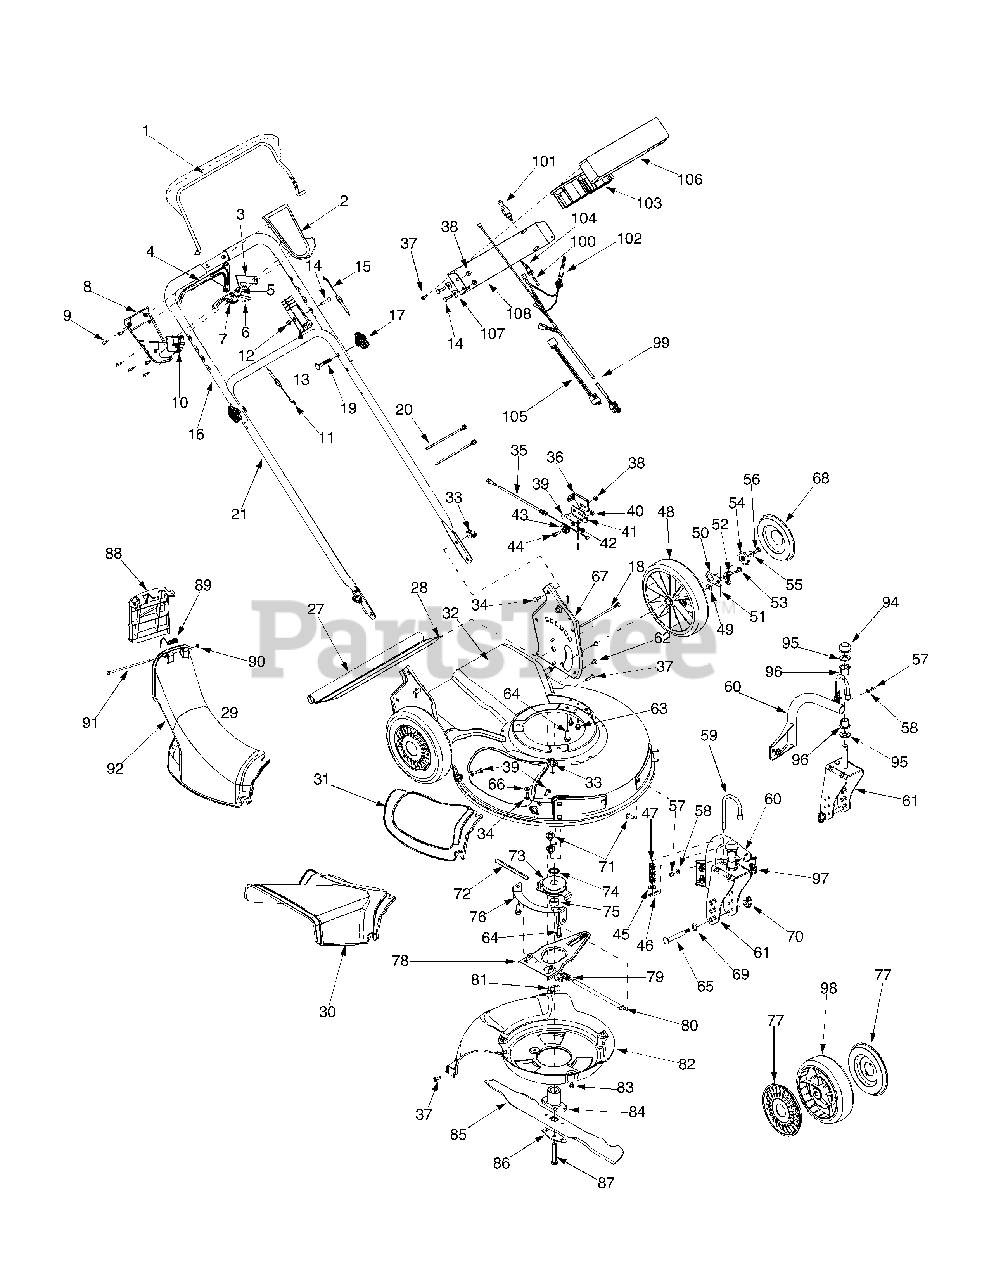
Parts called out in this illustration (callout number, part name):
1	Control Handle
2	Upper Control Handle
3	6 Spd. Rack Cable Bracket
4	Control Lever
5	Gear Insert
6	Shift Lever Spring
7	6 Speed Shift Lever
8	Lower Control Housing
9	C Sunk Tap Screw #10 x.75 Lg
10	Cable Mounting Cap
11	Drive Cable 51.0
12	Top Lock Nut 1/4-20
13	Control Housing
14	Screw, 1/4-20 x 1.50
15	Control Cable 49"
17	Star Knob
18	Cable Tie
19	Carriage Bolt 5/16-18 x 2.0
20	Cable Tie
27	Trail Shield
28	Trail Shield Wire
29	Chute Assembly
30	Side-Discharge Chute
31	Mulch Cover
33	Wing Nut
34	Carriage Bolt 1/4-20 x.75
35	6 Speed Cable
36	Cable Adjustment Bracket
37	Screw, #12-16 x 1.00
38	Flange Lock Nut, 1/4-20
39	Carriage Screw 1/4-20 x.62
40	Hex Nut 1/4-28
41	Cable Mounting Bracket
42	Lock Washer 1/4
43	Roller Cable
44	Shoulder Screw.340 x.335 x C
45	Flat Washer.330 ID x.630 OD
46	Cotter Pin
47	Compression Spring
48	Wheel 9 x 2.125
49	Top Lock Tab Weld Nut 1/4-20
50	Ratchet Pawl Plate
51	Plastic Spring Ratchet
53	Shld Screw.340 ID x.285 OD
54	Wheel Rachet
55	Bell Washer.265 ID x.75 OD
56	Hex Cap Screw 1/4-20 x.620
57	Grease Fitting
58	Flat Washer.203 ID x.403 OD
59	Wheel Pin Lock
60	Caster Assembly RH
60	Caster Assembly LH
61	Caster Bracket Assembly RH
61	Caster Bracket Assembly LH
62	Screw, 1/4-14 x.500
63	Screw, 1/4-20 x.625
64	Hex Washer Screw 3/8-16 x 1.0
65	Caster Axle
67	Handle Bracket Assembly - RH
67	Handle Bracket Assembly - LH
68	Hubcap - Radial Spoke
69	Wave Washer,.531ID x.781OD
70	Wing Nut
71	Carriage Bolt 5/16-18 x.62
72	Belt 3/8 x 39.24
73	Pulley Assembly
74	Sleeve Spacer.88 ID x 1.13 OD
75	Sleeve Spacer.88 ID x 1.00 OD
77	Hubcap - Spoke w/ Hole
80	Pivot Shaft
81	Wave Washer 1.38 ID x.88 OD
82	Baffle
83	Screw 1/4-20 x 3.75
84	Blade Adapter
85	21" Mulching Blade
86	Blade Bell Support
87	Hex Bolt 3/8-24 x 2.5
88	Chute Door
89	Torsion Spring
91	Pivot Rod
92	Discharge Chute
95	Flat Washer.640 ID x 1.12 OD
96	Flange Bearing
97	Flange Lock Nut, 5/16-18
98	Wheel 7 x 2
99	Electric Starter Harness Assembly
100	7.5 Amp Fuse
101	Key Switch
103	12 Volt Battery
104	Fuse Holder
105	Extension Harness
106	Upper Battery Tray
107	Saddle Washer,.320 x.93 x.060
108	Lower Battery Tray
